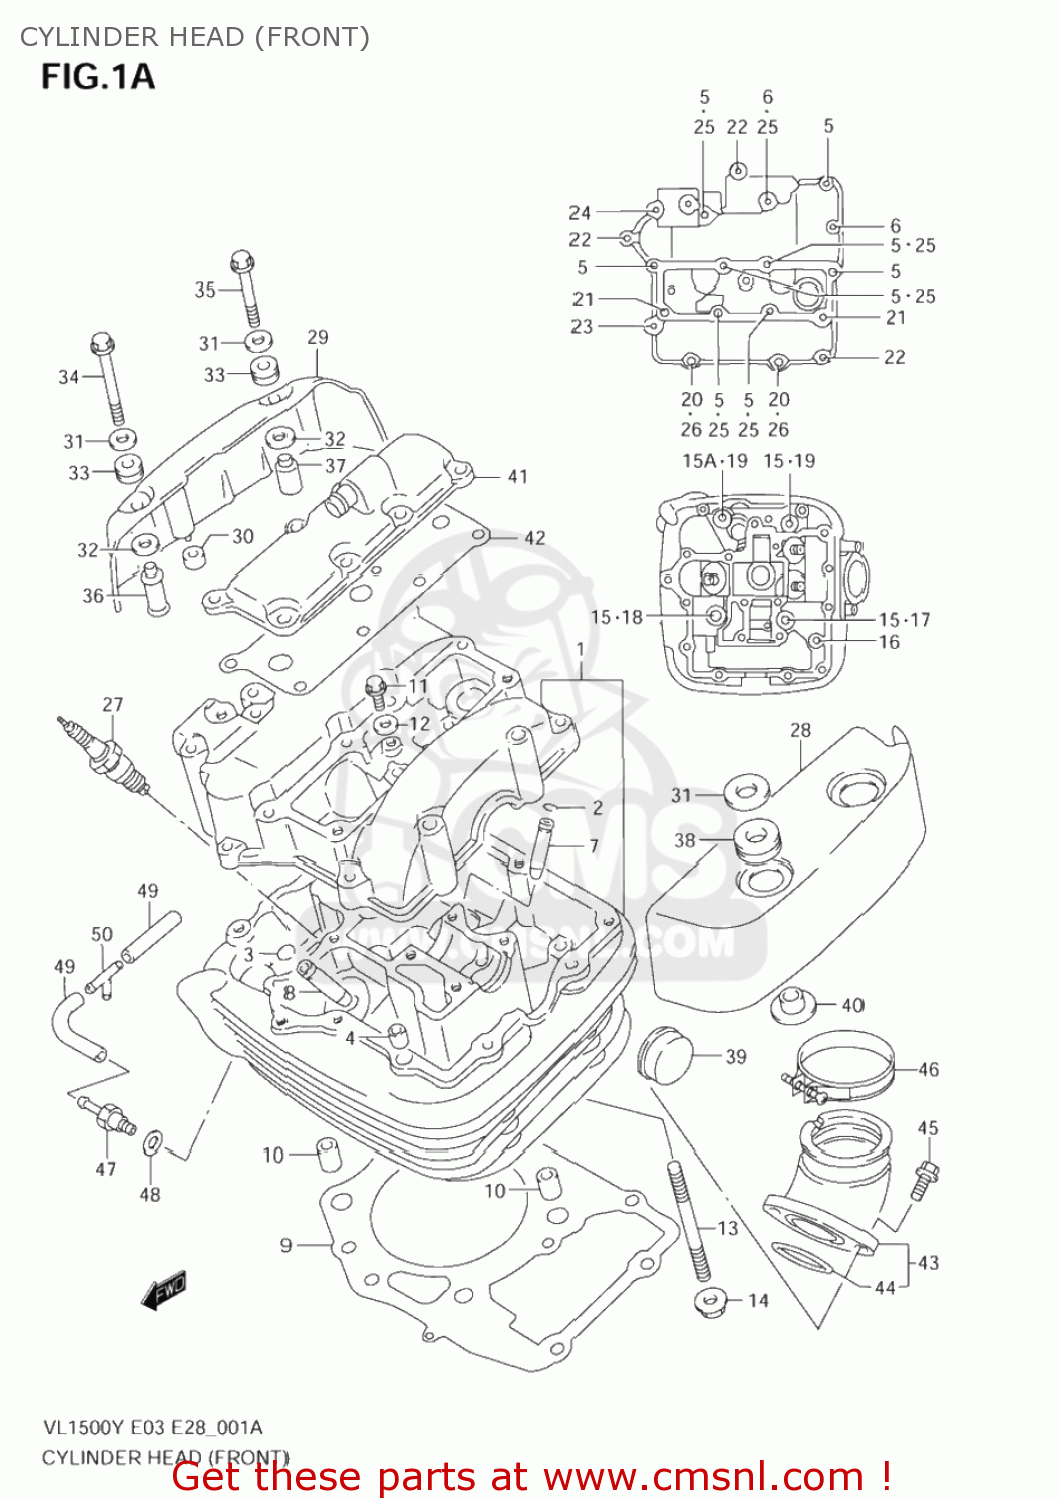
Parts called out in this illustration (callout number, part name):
1	HEAD ASSY,CYLINDER FR
2	RING,SNAP
3	RING,SNAP
4	PIN(6.2X8X11)
5	BOLT(6X60)
6	BOLT(6X55)
7	GUIDE,INTAKE VALVE
8	GUIDE,INTAKE VALVE
9	GASKET,CYLINDER HEAD FR (NAS)
10	PIN
11	BOLT
12	GASKET(6.2X13X1.2) (NAS)
13	BOLT,STUD
14	NUT
15	WASHER(10.5X22X2.3)
15A	GASKET(10.5X22X2) (NAS)
16	BOLT(8X70)
17	BOLT(10X180)
18	BOLT(10X190)
19	BOLT(10X200)
20	BOLT(8X268)
21	BOLT
22	BOLT
23	BOLT
24	BOLT
25	GASKET(5.8X13X1.2) (NAS)
26	WASHER(8.5X24X1.6)
27	SPARK PLUG X22E
28	CAP,CYLINDER HEAD COVER FR,L
29	CAP,CYLINDER HEAD COVER FR,R
30	CUSHION,R CAP
31	WASHER(6.5X18X1.6)
32	WASHER(9.5X20X1)
33	CUSHION
34	BOLT
35	BOLT
36	SPACER,CYL HEAD COVER CAP NO.1
37	SPACER,CYL HEAD COVER CAP NO.2
38	CUSHION
39	PLUG(OD:30)
40	BUSH
41	COVER,BREATHER
42	GASKET,BREATHER COVER (NAS)
43	PIPE ASSY,INTAKE FR
44	O RING(D:1.9,ID:40.7)
45	BOLT(6X16)
46	CLAMP
47	BOLT UNION
48	GASKET(6.2X13X1.2) (NAS)
49	HOSE(3.5X7.5X600)
50	3 WAY
